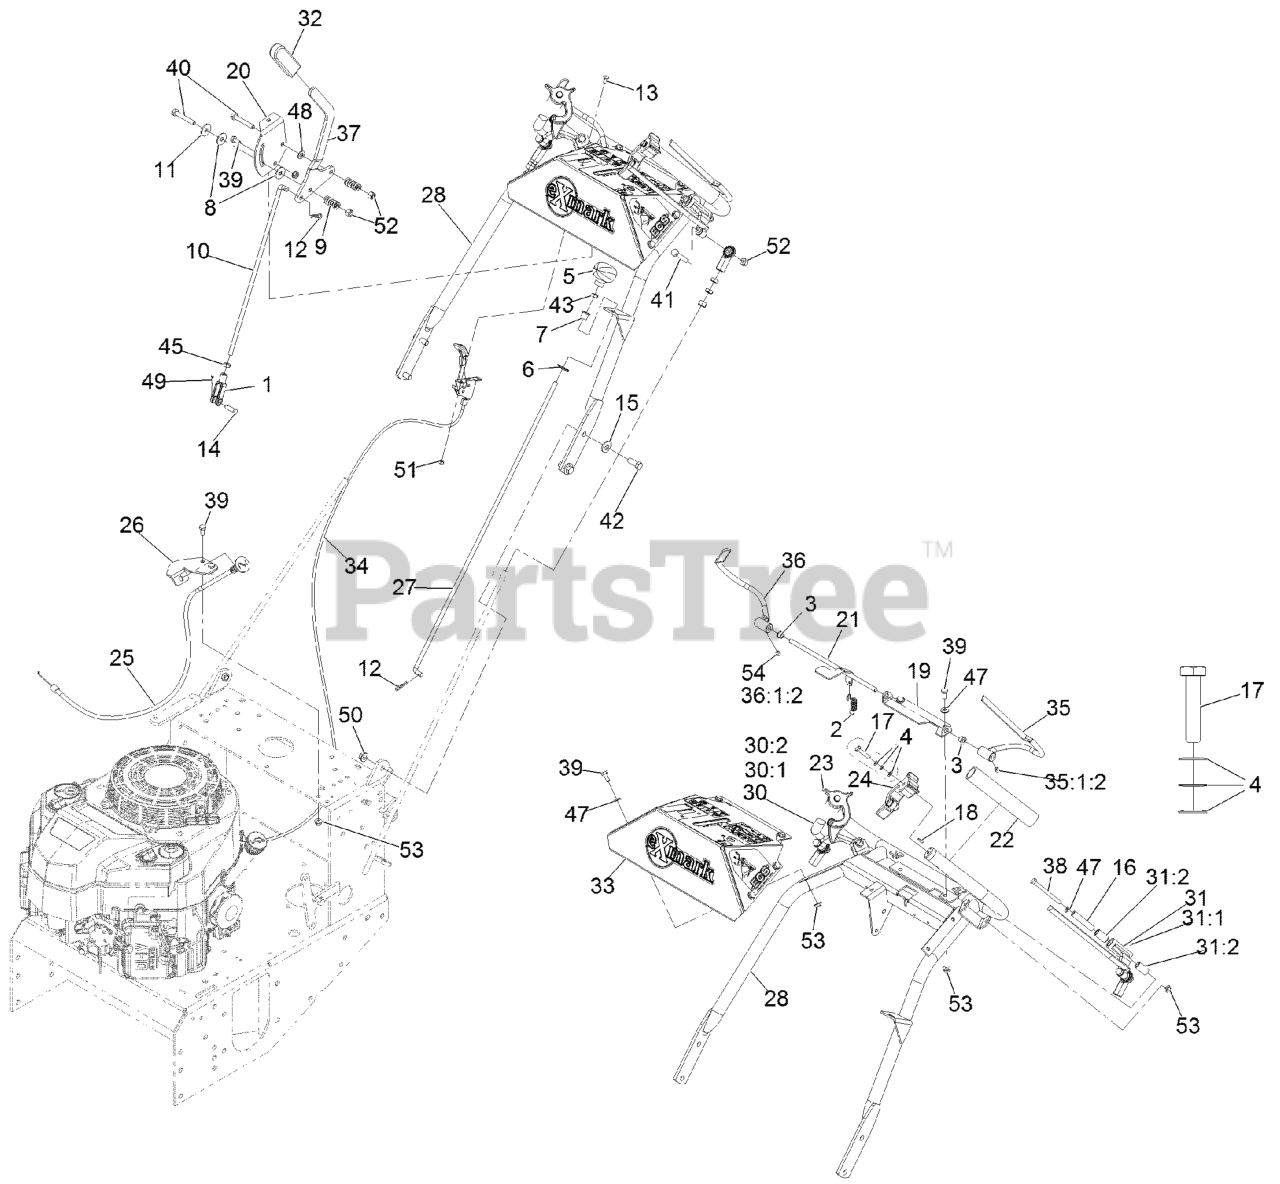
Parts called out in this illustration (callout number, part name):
1	YOKE-ADJUSTABLE
2	SPRING-EXTENSION
3	BUSHING-NYLON
4	WASHER-SPRING
5	KNOB-PUSH / PULL
6	NUT-PUSH
7	BEARING-NYLON
8	WASHER-FRICTION
9	SPRING-COMPRESSION
10	ROD-CONTROL, SPEED
11	WASHER-FRICTION
12	PIN-COTTER
13	BOLT-CARR
14	PIN-CLEVIS
15	WASHER-BELLEVILLE
16	BUSHING-LEVER, DRIVE
17	SCREW-HH
18	PIN-SPRING
19	BRACKET,OPC AXLE
20	BRACKET,SHIFTER SLIDE (PL
21	WLD,OPC LEVER AXLE
22	GRIP-BAR, HANDLE
23	ASM,LATCH RH THUMB
24	ASM,LATCH LH THUMB
25	CABLE-CHOKE
26	BRACKET-CABLE, CHOKE
27	LINKAGE,BLADE PUSH/PULL
28	WLD,VH ECS HANDLE
30	DRIVE LEVER-ASM, RH
30:1	WLD,RH DRIVE LEVER
30:2	BUSHING, SLEEVE
31	DRIVE LEVER-ASM, LH
31:1	WLD,LH DRIVE LEVER
31:2	BUSHING, SLEEVE
32	GRIP-HANDLE, STEERING
33	ASM,CONSOLE W/DECALS
34	CONTROL, THROTTLE
35	WLD,LH OPC LEVER
35:1:2	SCREW-SET
36	WLD,RH OPC LEVER
36:1:2	SCREW-SET
38	SCREW-HH
39	SCREW-HH
40	SCREW-HH
41	SCREW-HH
42	SCREW-HH
43	NUT-JAM
45	NUT-JAM
47	WASHER-FLAT
48	WASHER-PLAIN
49	PIN-COTTER
50	NUT-HHF, WHIZ
51	NUT-LOCK, NI
52	NUT-LOCK, NI
54	SCREW-SET
